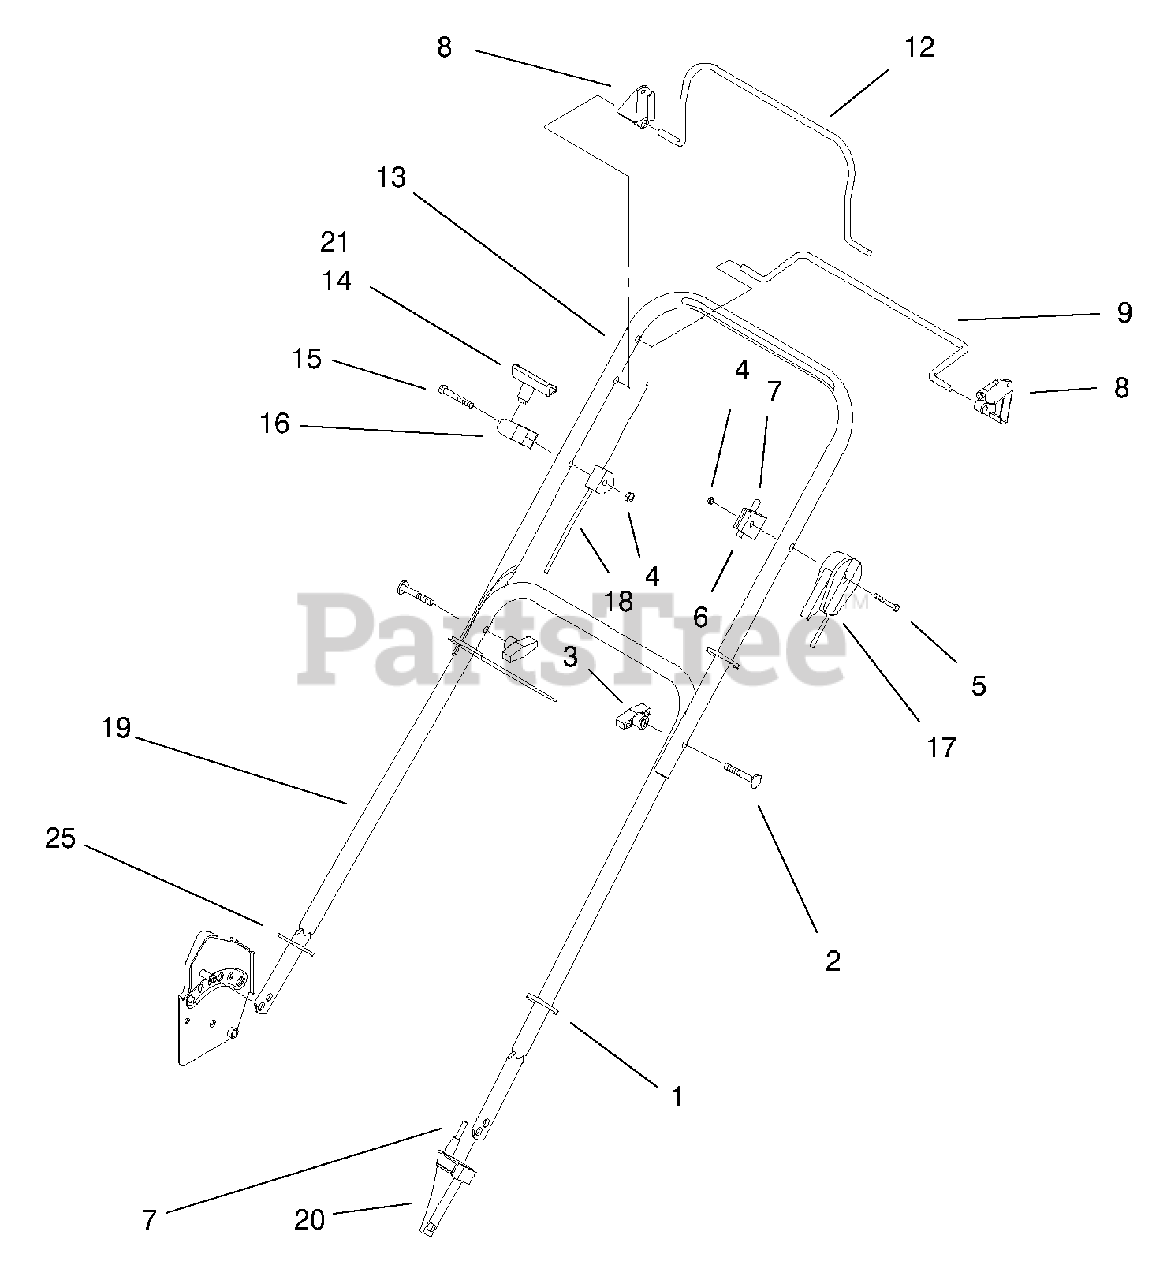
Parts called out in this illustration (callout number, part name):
1	Strap-Tie Sm
2	Screw-HH
3	Knob-Handle
4	Nut-Lock NI
5	Screw-Hex Hd
6	Anchor-Upper Sp Cable
7	Cable-Traction
8	Stop-Pivot
9	Bail-Sp Control
12	Bail-Brake
13	Handle-Upper
14	Handle-Start Eat
15	Screw-HH
16	Rope-Guide
17	Cable-Throttle
18	Cable-Flywheel Brake
19	Section-Lower Handle
20	Anchor-Cable
21	Starter-Clip Eat
25	Guard-Handle
